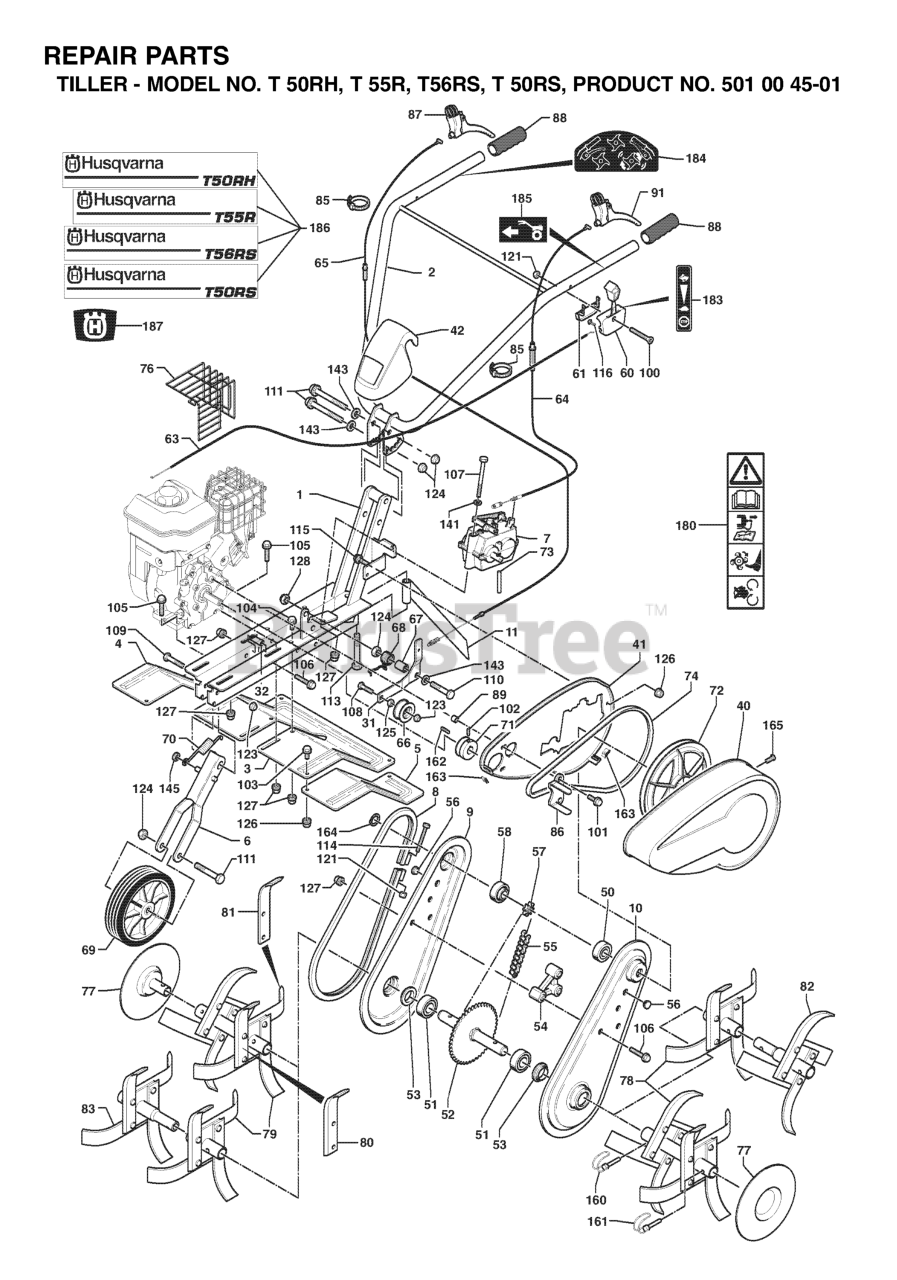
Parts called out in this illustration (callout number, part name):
1	CHASSIS PUBERT 3002070601
2	HANDLEBAR PUBERT 3002070602
31	ARM
42	COVER HANDLE BAR
55	DRIVE CHAIN
60	THROTTLE TRIGGER
61	THROTTLE CONTROL
64	CABLE GEAR PUBERT 0308010005
65	CABLE PUBERT 0308020043
69	WHEEL
91	GEAR SHIFT LEVER PUBERT 03070
121	Blocking nut M 6 Z
164	RETAINING RING
187	LABEL PUBERT 0503060004
